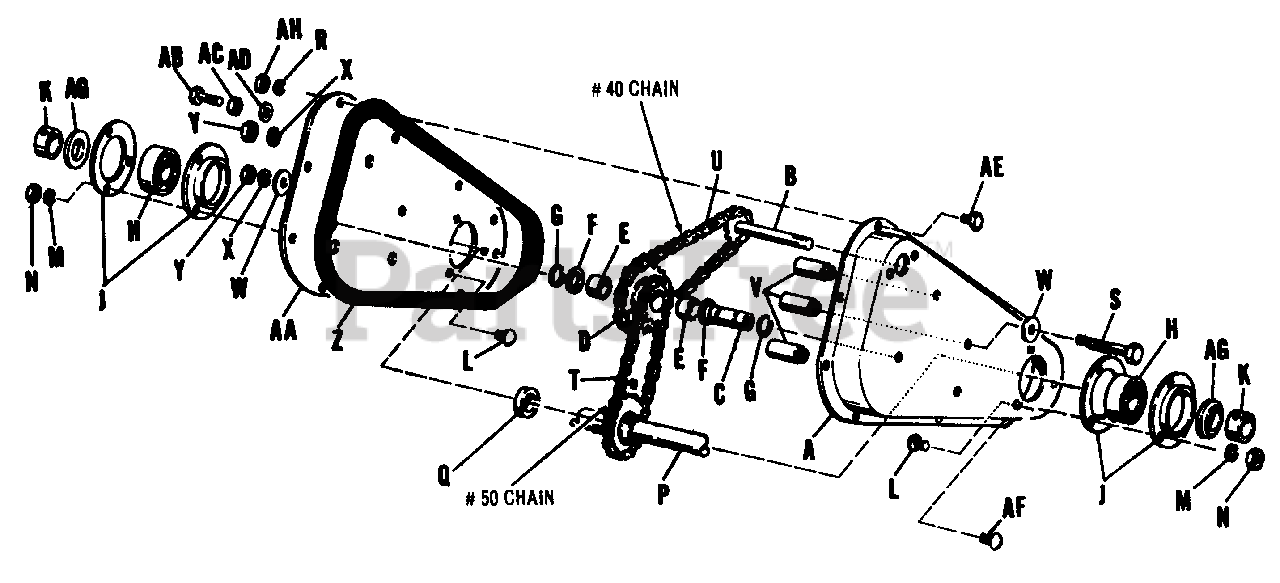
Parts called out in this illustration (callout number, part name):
A	Guard Assembly, Chain
B	Shaft Assembly Drive
C	Spacer, Intermediate
D	Sprocket Assembly
E	Bearing, Roller
G	Ring Retaining
J	Flange, Bearing
K	Collar, Bearing
L	Bolt Carriage, 3/8"-16 NC x 3/4" lg.
M	Washer Lock 3/8"
N	Nut, Hex, Full 3/8"-16 NC
P	Tine Shaft Assembly
R	Washer, Lock 5/16"
S	Capscrew Hex, 7/16"-14 NC x 3-3/4" lg.
T	Chain, Rotor
U	Chain, Drive
V	Spacer, Guard
X	Washer, Lock 7/16"
Y	Nut, Hex, Full 7/16" - 14 NC
AA	Plate Assembly
AB	Capscrew, Hex,3/8"- 24 NF x 2-1/2" lg.
AC	Nut, Hex, Jam, 3/8"- 24 NF
AD	Washer Plain 3/8"
AE	Capscrew, Hex, 5/16"- 18 NC x 5/8" lg.
AF	Carriage, Bolt 5/16"- 18 NC x 3/4" lg.
AH	Nut, Hex, Full 5/16"-18 NC
